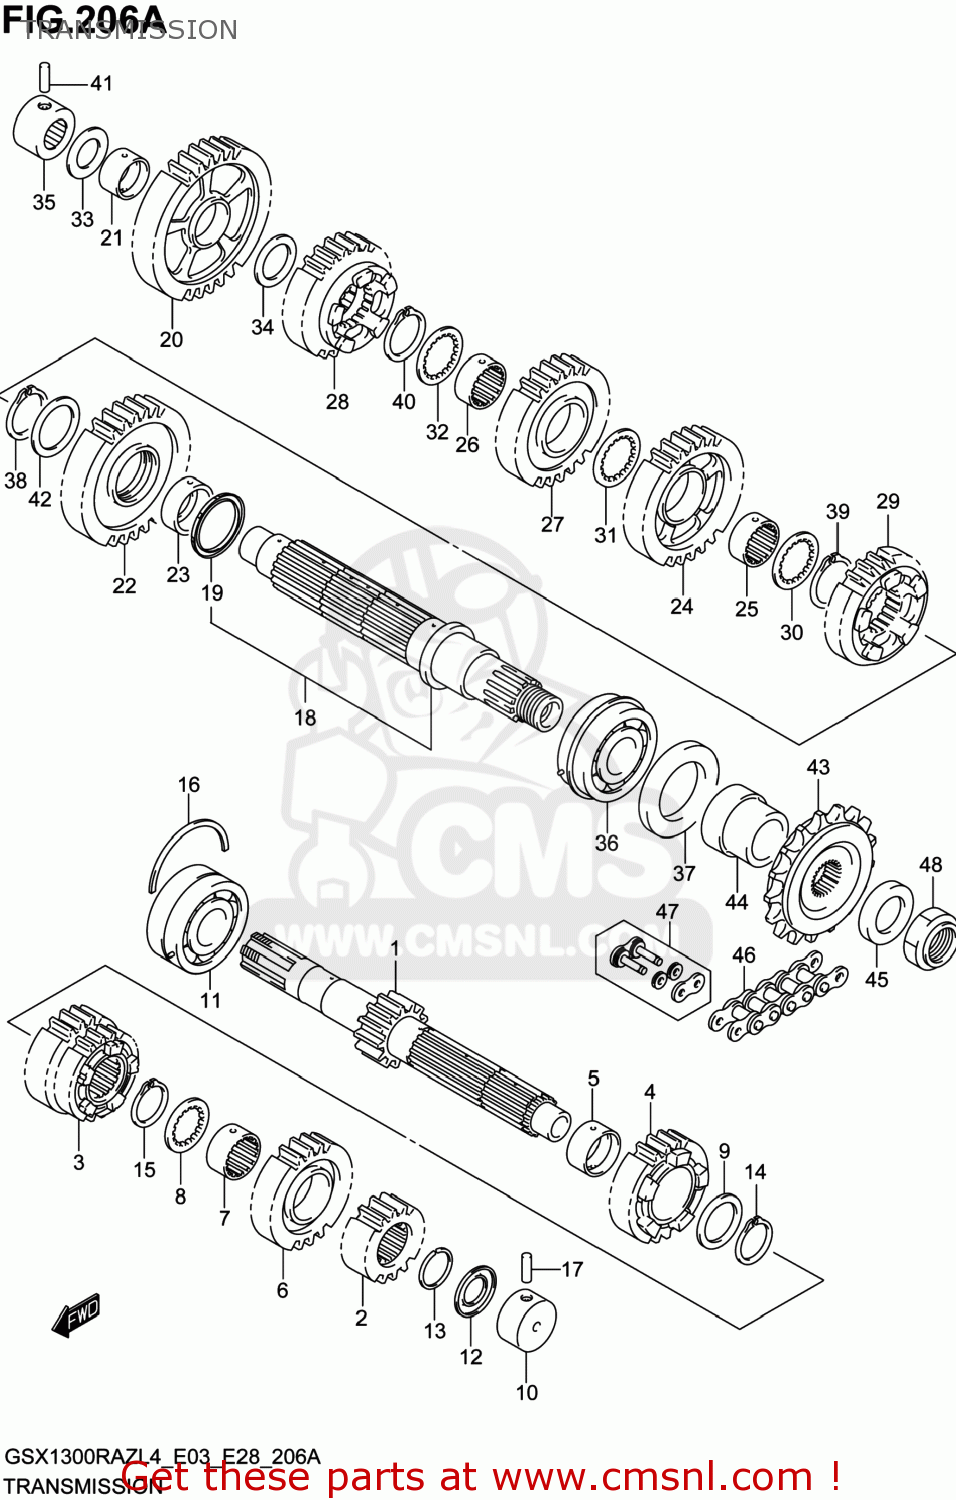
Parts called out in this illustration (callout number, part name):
1	SHAFT,COUNTER
2	GEAR,2ND DRIVE
3	GEAR,3RD & 4TH DRIVE
4	GEAR,5TH DRIVE
5	BUSH,5TH DRIVE GEAR
6	GEAR,6TH DRIVE
7	BUSH,6TH DRIVE GEAR
8	WASHER,LOCK
9	SHIM(27X36X2.5)
10	BEARING(20X34X17.5)
11	BEARING(25X62X25.4)
12	SEAL,OIL(20X31.2X2.7)
13	CIRCLIP
14	CIRCLIP
15	CIRCLIP
16	C RING
17	PIN
18	SHAFT,DRIVE
19	RING,DRIVE SHAFT FRICTION
20	GEAR,1ST DRIVEN
21	BUSH,1ST DRIVEN GEAR
22	GEAR,2ND DRIVEN
23	BUSH,2ND DRIVEN GEAR
24	GEAR,3RD DRIVEN
25	BUSH,DRIVEN GEAR
26	BUSH,DRIVEN GEAR
27	GEAR,4TH DRIVEN
28	GEAR,5TH DRIVEN
29	GEAR,6TH DRIVEN
30	WASHER,LOCK
31	WASHER,LOCK
32	WASHER,LOCK
33	SHIM(20X34X1)
34	SHIM(24X34X1)
35	BEARING(20X34X20)
36	BEARING(30X62X23.8)
37	SEAL,OIL(42X62X7)
38	CIRCLIP
39	CIRCLIP
40	CIRCLIP
41	PIN
42	WASHER
43	SPROCKET,ENGINE(18T)
44	SPACER,ENGINE SPROCKET NO.1
45	SPACER,ENGINE SPROCKET NO.2
46	CHAIN,DRIVE
47	JOINT SET,CHAIN
48	NUT
